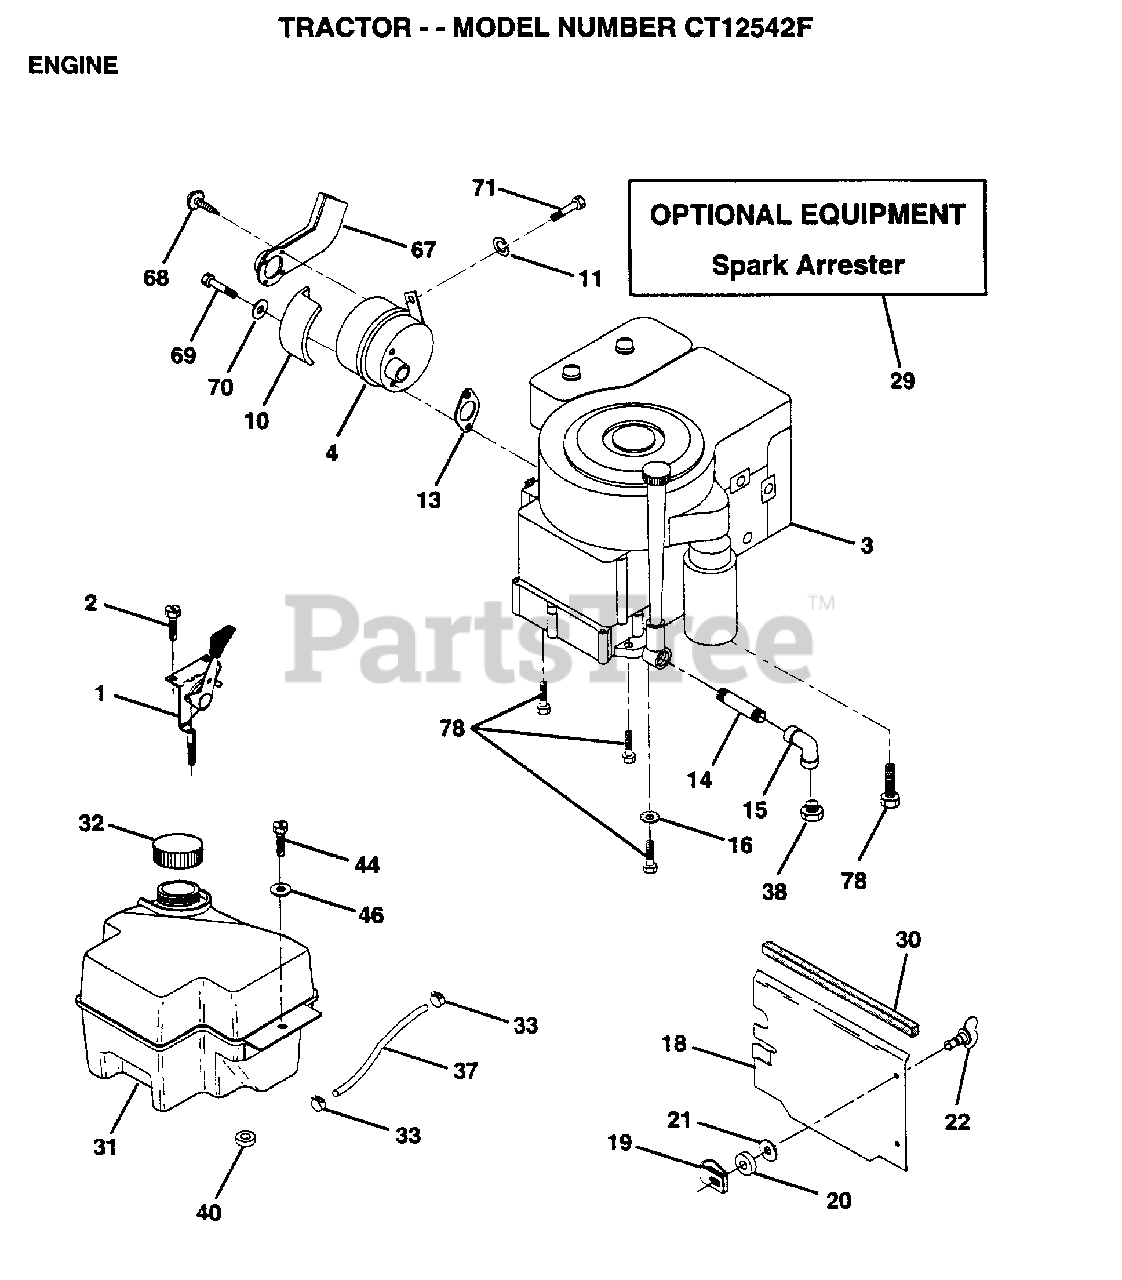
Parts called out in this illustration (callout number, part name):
1	CONTROL THROTTLE
2	SCREW LT
4	MUFFLER LTV
10	SHIELD HEAT LTV
11	LOCKWASHER
14	PIPE NIPPLE
15	ELBOW
16	LOCKWASHER
17	SCREW
32	CAP ASM FUEL
33	HOSE CLAMP
37	LINE FUEL
44	SCREW HEX CRT
46	WASHER
67	DEFLECTOR MUFFLER
69	"BOLT,HEX"
70	WASHER T
71	BOLT HXHD FIN
